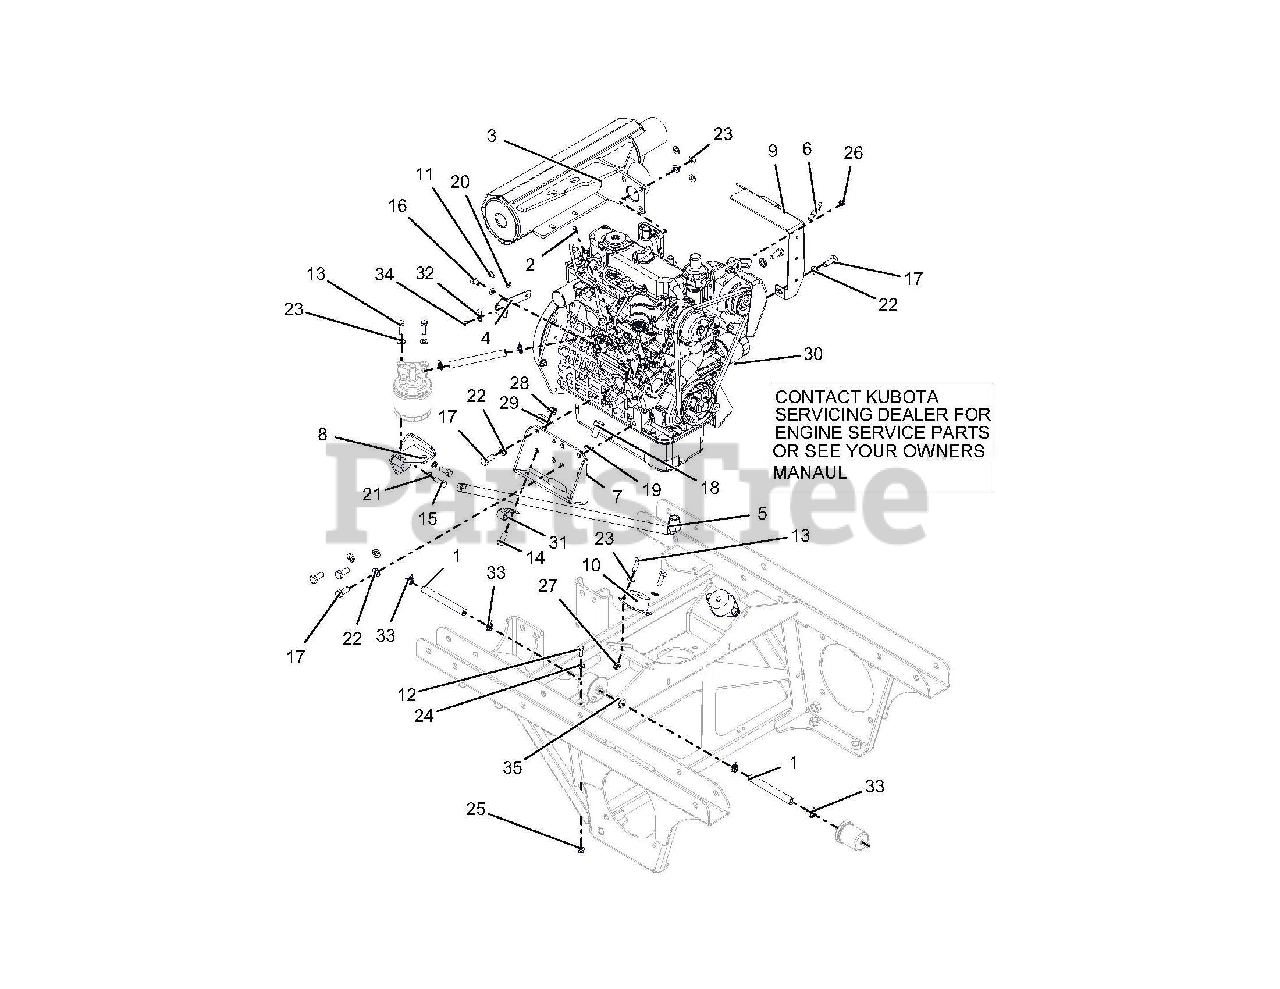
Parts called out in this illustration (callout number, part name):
1	HOSE, .31 ID X
2	SWIVEL, ASM
3	MFLR, DIESEL PT-400
4	BRKT, THROTTLE CABLE -
5	HOSE, ASM DIESEL OIL DRAIN
6	SENDER, WATER TEMPERATURE
7	WLDMT, FRONT ENGINE MOUNT
8	WLDMT, DIESEL FUEL FILTER MOUNT
9	BRKT, HEAT DEFLECTOR LOUVERED
10	MOUNT, ENGINE. VIBRATION ISO
11	BLT-HEX M6 X 1.0X10 YWZC
12	BLT-HEX .25-20X.75 GR5 YWZC
13	BLT-HEX .31-18X1.00 GR5 YWZC
14	BLT-HEX .38-16X1.00 GR5 YWZC
15	BLT, HEX M8-1.25X25 GR8.8YWZC
16	@BLT-HEX M8 X 1.25X14 YWZC
17	BOLT, HEX M10-1.25 X 25 YWZC
18	BLT-HEX .50-20X1.00 GR5 YWZC
19	WSHR-LK .50X.125 REG YWZC
20	WSHR-LK .25X.062 REG YWZC
21	WSHR-LK .31X.078 REG YWZC
22	WSHR-LK .44X.109 REG YWZC
23	WSHR-FL-STL.344X.688X.065YWZC
24	WSHR-FL-STL.281X.62X.065 YWZC
25	NUT-LK-NYL-FLG .25-20 YWZC
26	NUT-HEX M6-1.00 YWZC
27	NUT-LK-NYL-FLG .31-18 YWZC
28	NUT-LK-NYL-FLG .38-16 YWZC
29	CLAMP, J
30	ASM, KUBOTA D902 WITH FUEL FILTERS & ELE FUEL PUMP
32	CLIP, CABLE
33	HOSE, CLAMP DOUBLE WIRE
34	SCR, TAP 10-24X.375 PRE-COAT 80
35	GROMMET, RUBBER
